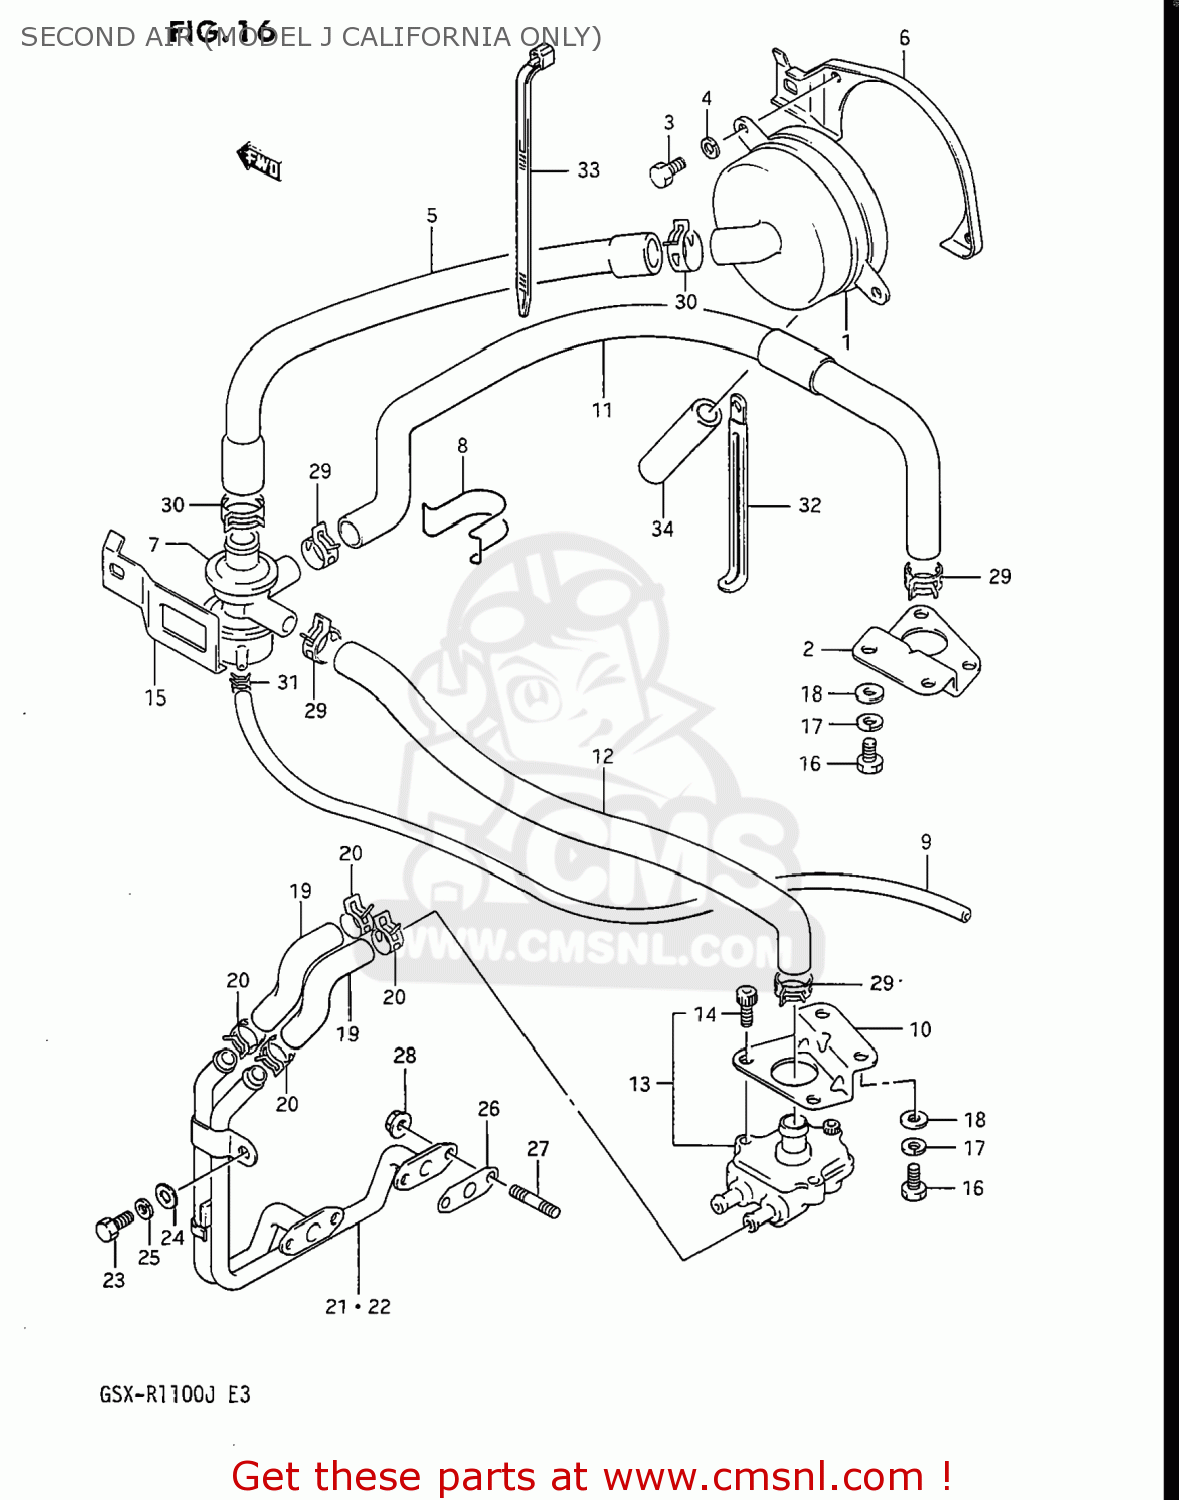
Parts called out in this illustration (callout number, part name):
1	CLEANER ASSEMBLY,SECOND AIR
2	HOSE,SECOND AIR VALVE
3	BOLT
4	WASHER
5	HOSE,SECOND AIR CLEANER
6	BRACKET,SECOND AIR CLEANER
7	VALVE ASSY,2ND AIR SWITCHING
8	CLAMP,SWITCHING VALVE
9	HOSE
10	BRACKET,SECOND AIR REED VALVE
11	HOSE,SECOND AIR VALVE NO
12	HOSE,SECOND AIR NO.2,LEFT
13	VALVE ASSY,2ND AIR REED
14	BOLT
16	BOLT
17	WASHER,LOCK
18	WASHER
19	(CA) HOSE,SECOND AIR NO.1
20	CLIP
21	PIPE ASSEMBLY,SECOND AIR
22	PIPE ASSEMBLY,SECOND AIR
23	BOLT
24	WASHER(6.5X16X1.2)
25	WASHER,LOCK
26	GASKET,SECOND AIR PIPE (NAS)
27	STUD BOLT
28	NUT 6MM
29	CLIP
30	CLIP
31	CLAMP
32	CLAMP
33	CLAMP(L:165)
